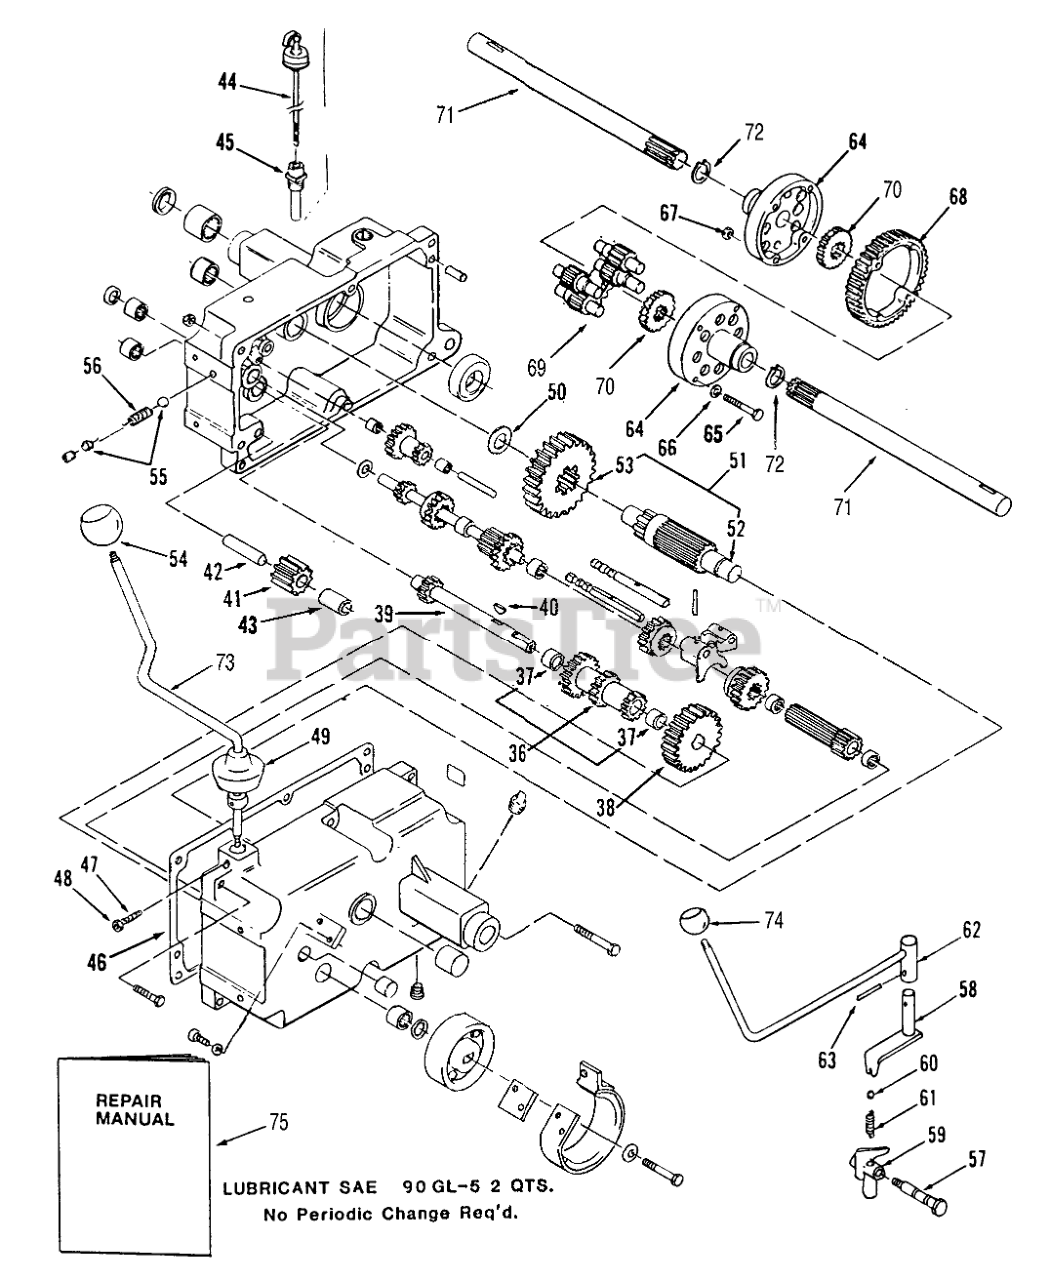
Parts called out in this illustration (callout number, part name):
36	GEAR-CLUSTER
37	BUSHING-BRONZE
38	GEAR-CLUSTER SHAFT
39	Cluster Shaft
40	KEY-WOODRUFF
41	GEAR/BUSHING ASM-REVERSE IDLER
42	PIN-DIFFERENTIAL
43	BUSHING
44	ASSY-DIPSTICK
45	NIPPLE-TRANS FILL
46	GASKET-TRANSMISSION
47	SETSCREW
48	Nut
49	COVER-DUST
50	WASHER-THRUST
51	GEAR ASM
52	PINION SHAFT
55	BALL-DETENT
56	SPRING-SHIFT STOP
57	BOLT-DETENT
58	SHIFT ASM
59	SHIFT FORK ASM
60	BALL-DETENT
61	SPRING-SHIFT STOP
62	SHIFT ROD ASM
63	PIN-SPIROL
64	END CAP-DIFFERENTIAL
65	BOLT-HEX
66	WASHER
68	GEAR-DIFFERENTIAL RING, 43T
69	GEAR-PINION, 11T
70	GEAR-AXLE DIFFERENTIAL
71	AXLE-REAR
72	RING-SNAP
73	ASM-Rod
74	Knob
75	MANUAL
